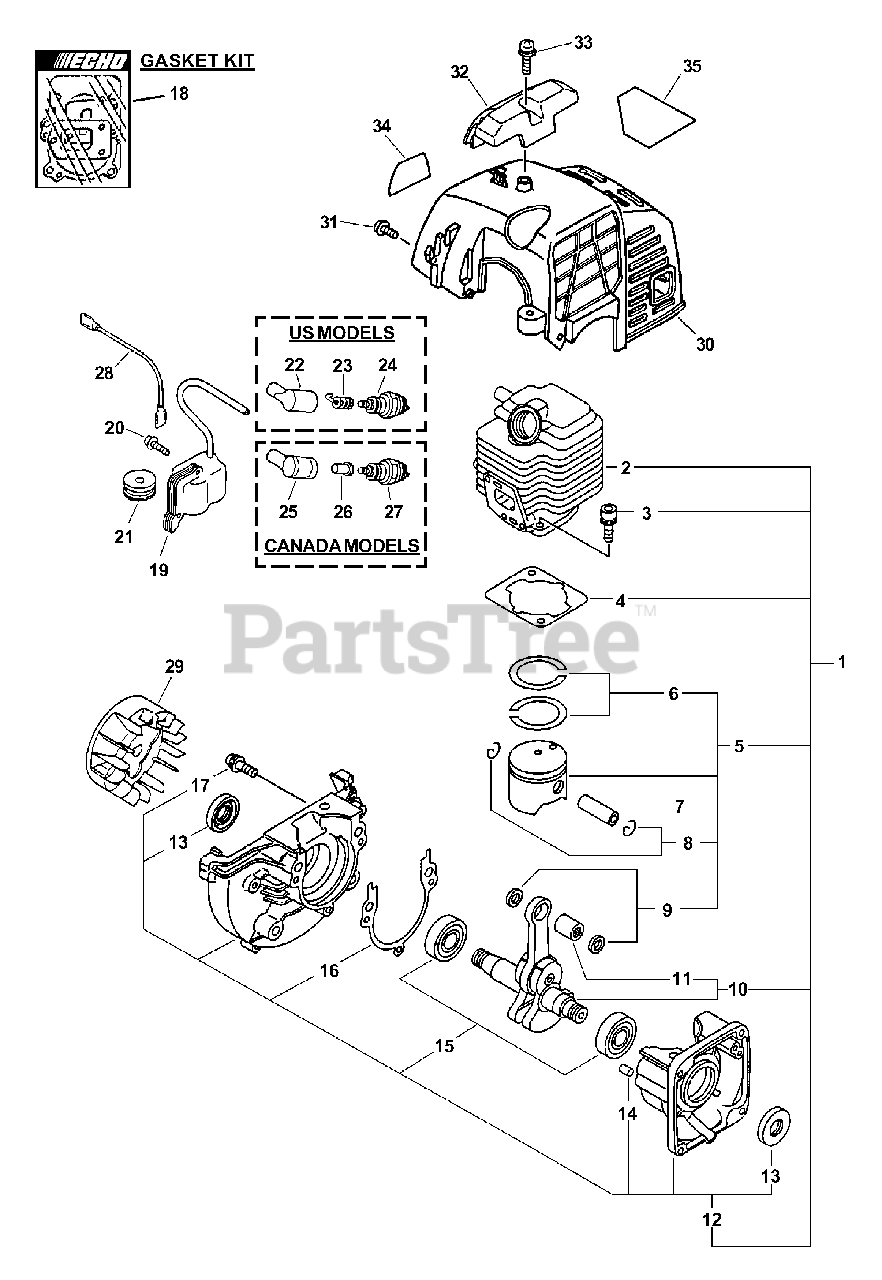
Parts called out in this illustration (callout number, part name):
1	SHORT BLOCK ES-2400
2	CYLINDER
3	BOLT 5×22
4	GASKET, CYLINDER
5	PISTON KIT
6	RING, PISTON
7	PIN, PISTON 8
8	RING, SNAP
9	WASHER, THRUST
10	CRANKSHAFT ASSY
11	BEARING, NEEDLE 8
12	CRANKCASE KIT
13	SEAL, OIL 12
14	PIN, LOCATING 4
15	BEARING, BALL - 6201 C3
16	GASKET, CRANKCASE
17	BOLT 5×28
18	GASKET KIT
19	COIL, IGNITION
20	SCREW 4×22
22	CAP, SPARK PLUG
23	TERMINAL, SPARK PLUG
24	SPARK PLUG - BPM-7Y
25	CAP, SPARK PLUG
26	ADAPTOR, SPARK PLUG - CAP
27	SPARK PLUG - BPMR7A
28	LEAD
28	FLYWHEEL
29	GUARD, ENGINE
30	COVER, ENGINE - ORANGE
31	SCREW 4×12
32	GUARD, TOP - BLACK
33	SCREW 5×16
34	LABEL, PPT-2400
35	LABEL, CAUTION
